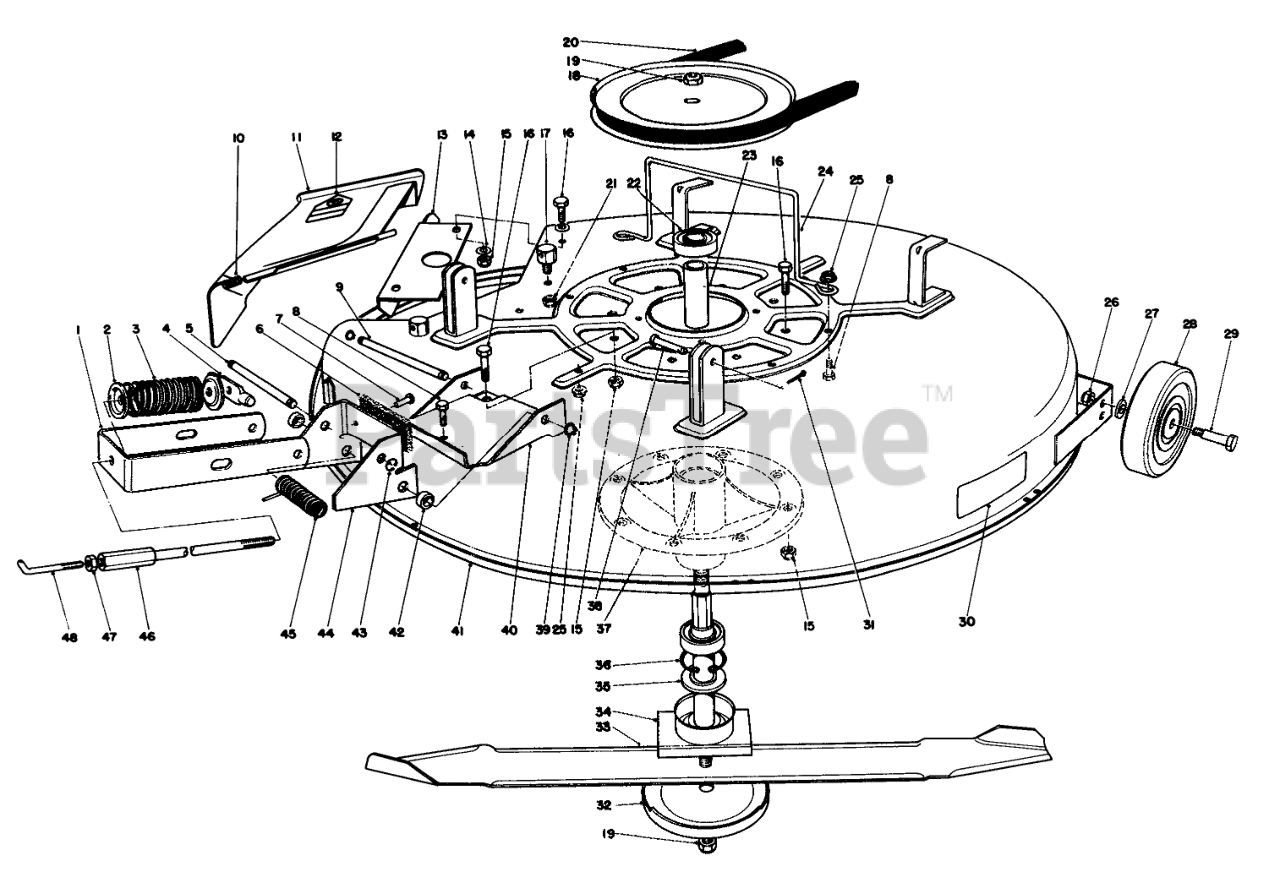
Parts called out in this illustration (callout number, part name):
1	Bracket-Engagement
2	RETAINER-SPR. TOP
3	SPRING-COMPRESSION
4	SHAFT-DECK ADJ.
5	Pin-Clevis
6	BRAKE PAD
7	Rivet
8	SCREW-HH
9	CLEVIS PIN
10	SPRING
11	Deflector Assembly (Incl. Ref. #12)
12	DECAL-DANGER
13	Baffle Deck
14	WASHER-PLAIN
15	NUT-LOCK, NI
16	Screw
17	POST-PIVOT
18	PULLEY
20	V-BELT, DECK
21	NUT-LOCK, SIDE
22	BEARING-BALL
23	Spacer-Bearing
24	Guide-Belt
25	NUT-LOCK, HHF
26	NUT-LOCK, NI
27	WASHER-FLAT
28	DECK WHEEL
29	BOLT-WHEEL
30	DECK DECAL
31	PIN-COTTER
32	Cup
33	Blade
34	SPINDLE SHAFT WA
35	SPACER-SPINDLE
36	RING-RETAINING
37	SPINDLE
38	PIN-CLEVIS
39	RING-RETAINING
40	DECK ENGAGE CHANNEL R
41	Cutter Deck
42	DECK BRAKE SPACER
43	E-RING
44	Support Deck Brake Assembly (Incl. Ref. #6 & 7)
45	SPRING
46	ADJ HUB WA
47	NUT-JAM
48	ADJ. ROD
